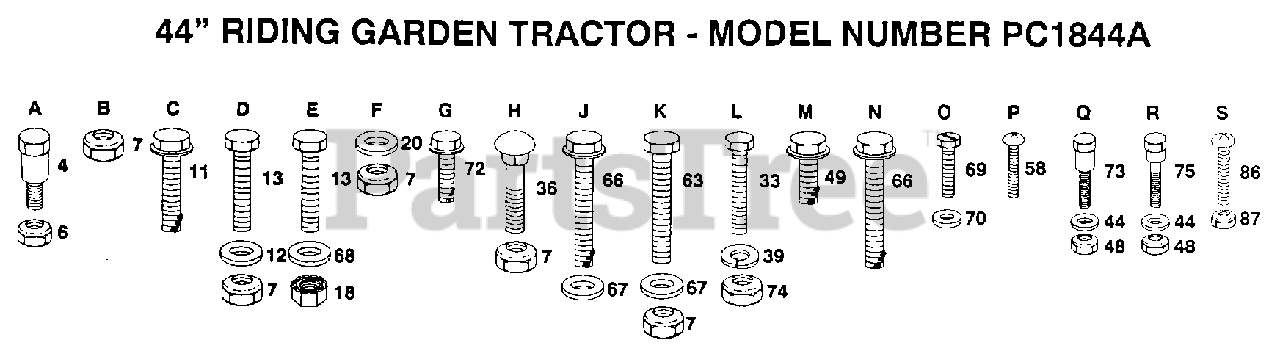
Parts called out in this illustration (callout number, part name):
11	SCREW
12	WASHER
18	NUT
20	WASHER
33	BOLT LT
36	BOLT
39	LOCKWASHER
49	SCREW LT
63	BOLT
66	SCREW GTV
67	WASHER HYT
68	WASHER
69	SCREW
73	BOLT T
75	"BOLT,SHOULDER"
87	"NUT,KEPS"
